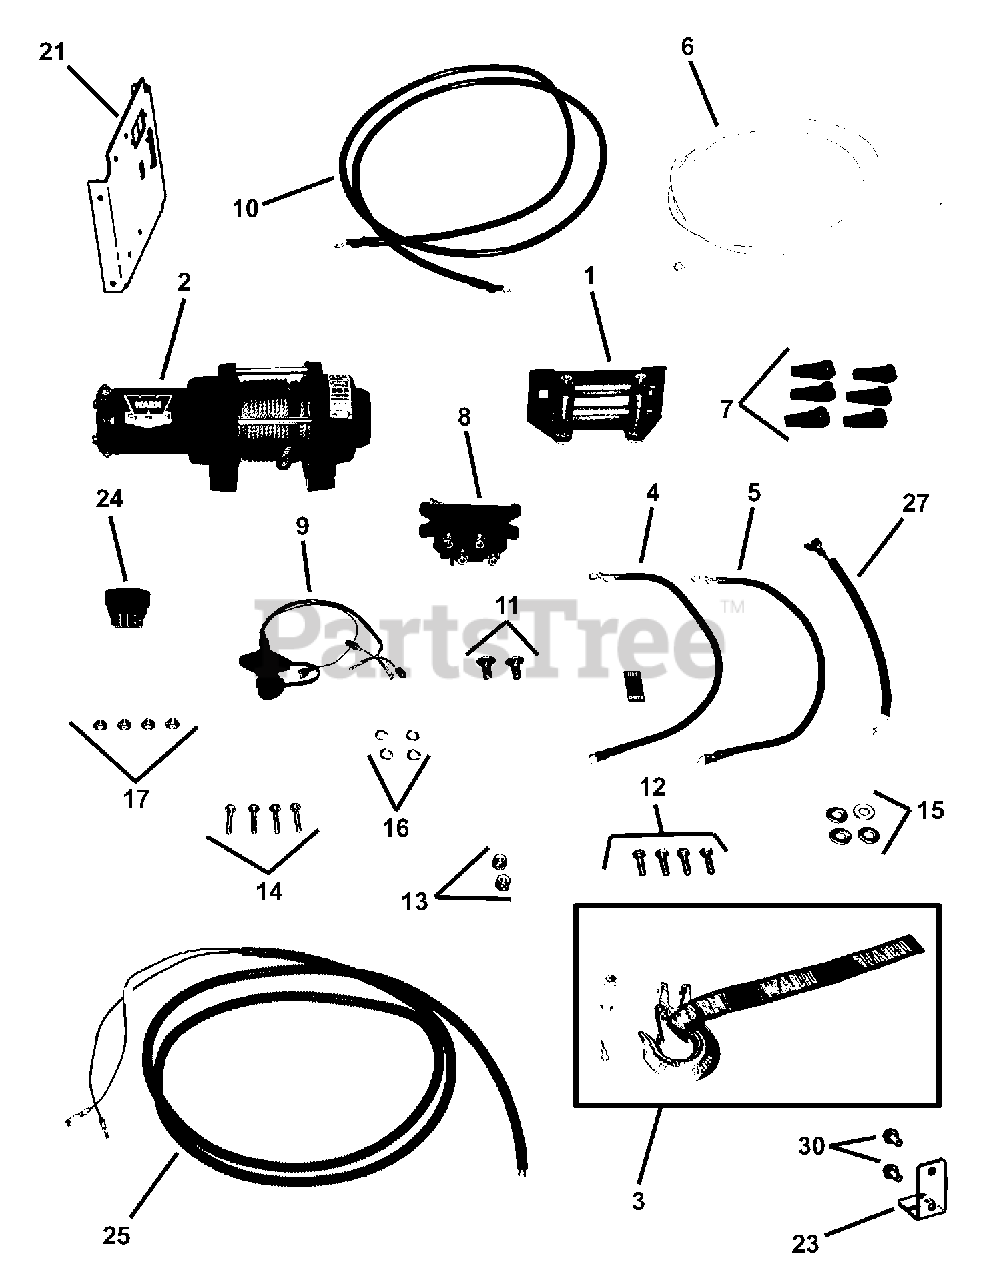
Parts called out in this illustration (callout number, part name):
1	ASSY., Winch Fairlead
2	WINCH, Warner 2.5 C.I.
3	KIT, Winch Hook
4	WIRE, Black, 6 Ga. 18" long
5	WIRE, Red, 6 Ga. 18" long
6	WIRE, Yellow, 6 Ga. 71" long
7	BOOT, Terminal Winch
8	CONTACTOR, 12V Winch
9	ASSY., Remote Socket w/Harness
10	WIRE, Blue, 6 Ga. 71" long
11	BOLT, 3/8-16 x 3/4" Sq. Neck Carriage
12	SCREW, 5/16-18 x 1" Hex Hd. Cap GR 5
13	NUT, 3/8-16 Hex Nyloc
14	SCREW, 1/4-20 x 1-1/4" Hex Hd. Cap
15	WASHER, .31 x .75 x .08 Flat
16	WASHER, 1/4" Split Lock
17	NUT, 1/4-20 Hex
21	WLDMT., Pwr. Gen. End Cap LH (Green)
23	THROTTLE ANCHOR, Front
24	SWITCH, Momentary Rocker (On-Off-On)
26	WINCH HARNESS, Main
27	WINCH HARNESS, Dash
30	SCREW, 5/16-18x3/4" Hex Washer Self-Tap
